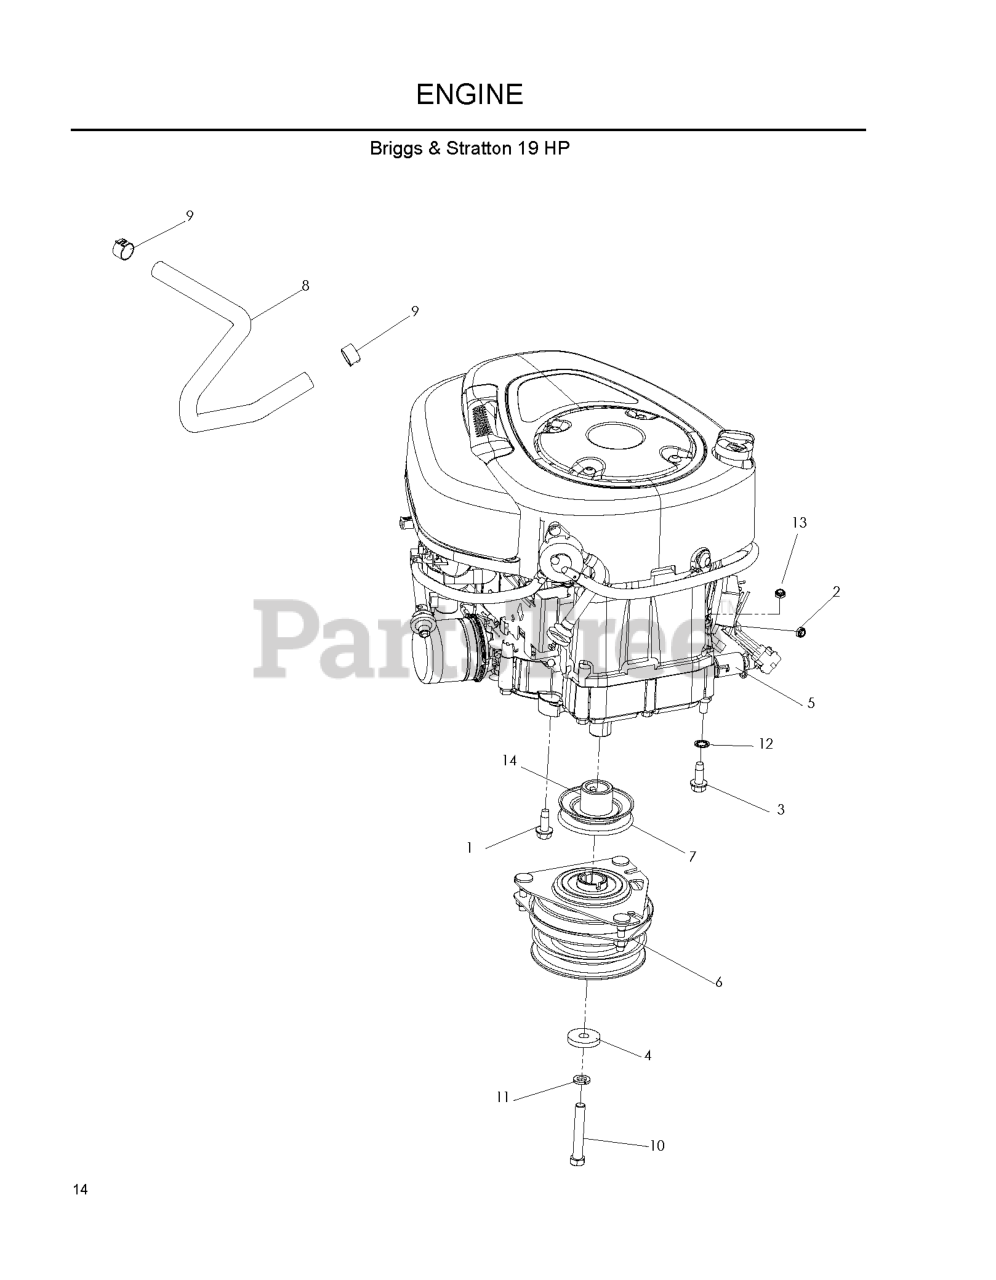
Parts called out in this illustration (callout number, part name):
1	BOLT 3/8-16 X 1.0
2	JAM NUT 1/4C (2 2 PW01)
3	BOLT 3/8-16 X 1 1/2 ZINC CLEAR
4	CLUTCH, WASHER
5	OIL DRAIN FITTING
6	CLUTCH 90 FT/LB OGURA
7	PULLEY, ENGINE
8	FUEL LINE 5"
9	HOSE CLAMP
10	HEX SCREW 7/16-20 X 3
11	WASHER 7/16 LOCK
12	WASHER, 3/8 ITLW ZN
13	NUT 3/8C CENTERBLOCK
14	SPACER, ENGINE - PULLEY
